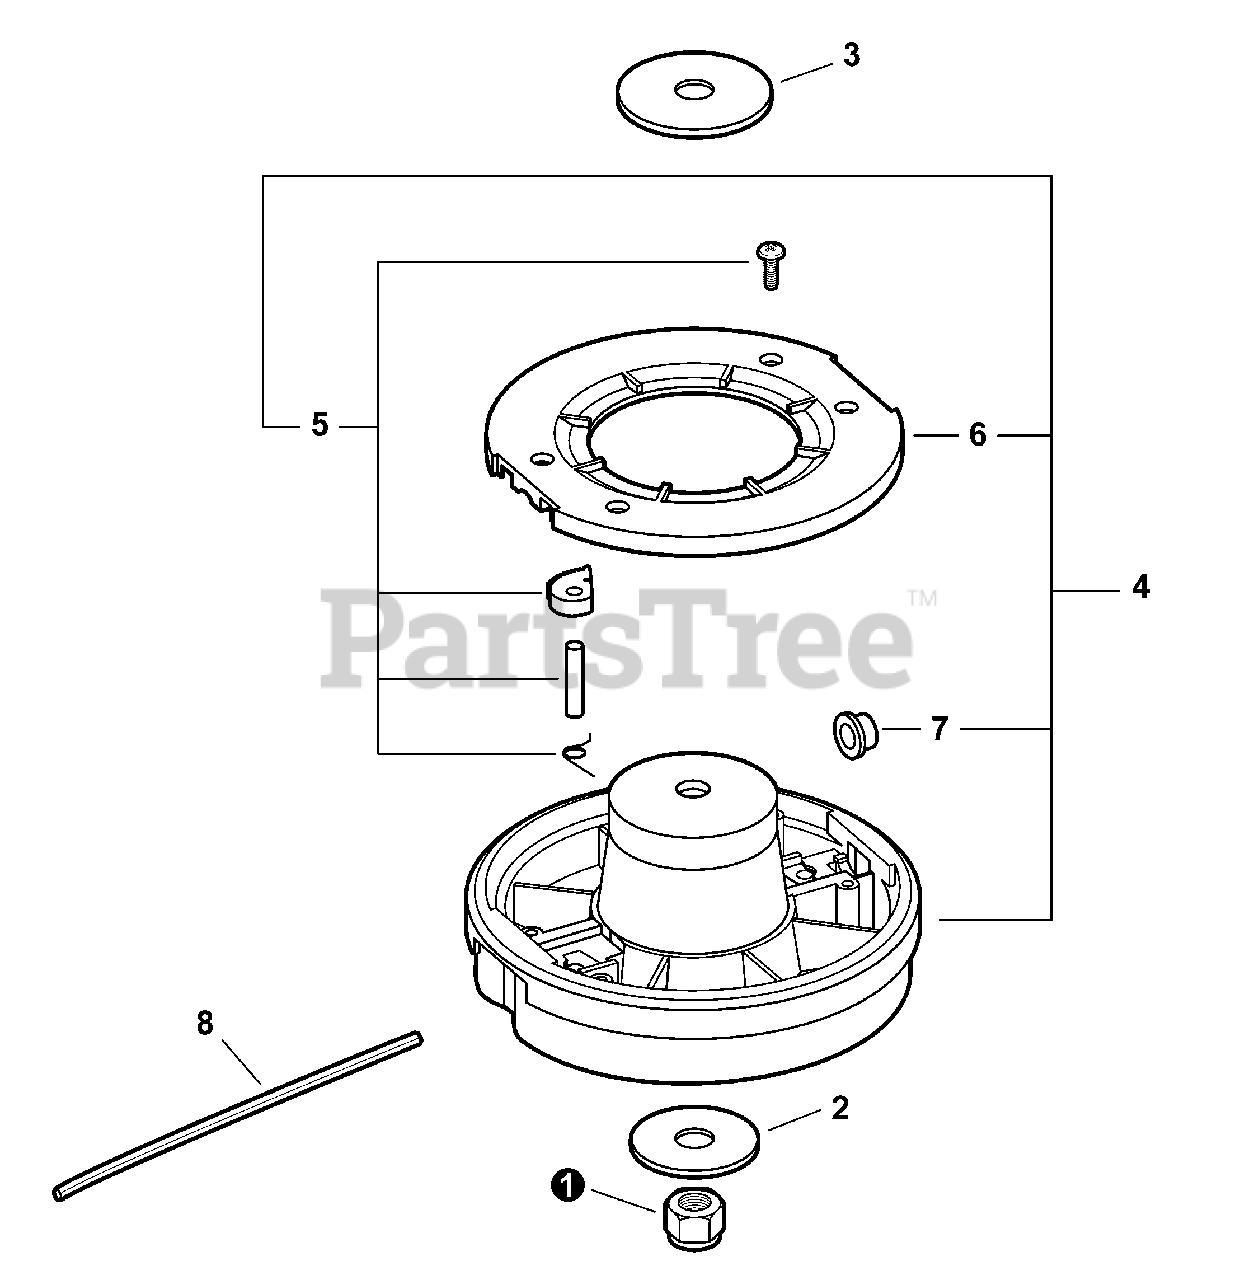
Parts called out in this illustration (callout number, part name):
1	LOCKNUT
2	WASHER - 8
3	WASHER - 10
4	TWO LINE RAPID LOADER ATTACHMENT
5	REPAIR KIT
6	COVER, TOP
8	LINE, CUTTING - 0.080in
